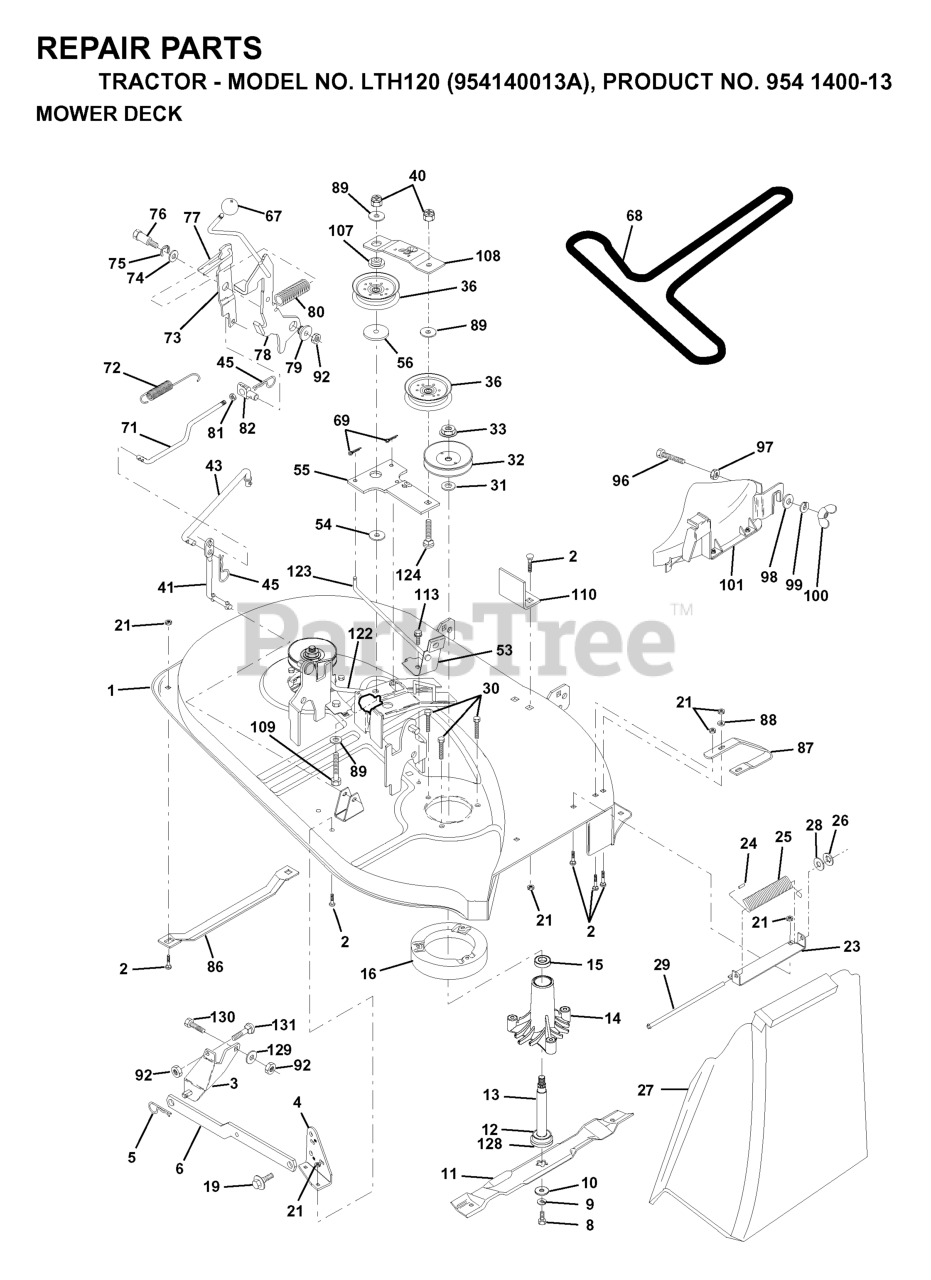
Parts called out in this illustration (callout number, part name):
1	DECK ASSY-WELDMENT
2	RP BOLT 5/16-18 X3/4 ZN/YEL GR
3	BRKT ASM SWAY BAR
4	BRKT DECK SW BAR
5	RETAINER-SPRNG RB
6	REAR SUSP ARM
8	BLADE BOLT
9	LOCKWASHER
10	WASHER.BLADE
11	BLADE 38" V MULCH
12	BEARING.BALL.#6204.(MANDREL)
13	SHAFT ASM VENT
14	HOUSING.MANDREL.VENTED (MACHD)
16	STRIPPER
19	BOLT SHD 5/16-18
21	LOCKNUT
23	BRACKET, DEFLECTOR
24	CAP-SLEEVE LT
25	SPRING TORSION
26	NUT PUSH M
27	SHIELD.DEFLECTOR.MOWER.38.BL
28	Washer 11/32 x 5/8 x 16 Ga SD
29	ROD-HINGE T
30	SCREW
31	WASHER
32	PULLEY MANDREL
33	NUT
36	FLAT IDLER PULLEY
43	CLUTCH ROD SECONDARY
45	RETAINER M
53	BRAKE ASSEMBLY
54	HARDENED WASHER
56	SPACER RETAINER
67	KNOB T (3/8 HOLE)
68	V-BELT TRIPATH
69	COTTER PIN
71	CLUTCH ROD
72	RETURN SPRING
73	ARM CLUTCH SECONDARY
77	KEEPER SPRING
78	ARM ASM CLUTCH PRIMARY
79	BUSHING.FLANGE.E-RING.GROOVE
80	SPRING-CLUTCH (2 2 PW01)
81	NUT
82	TRUNNION.ADJUSTABLE.3/8-16
86	RUNNER-LH M
87	RUNNER.RH.38
88	WASHER M
89	WASHER GT
92	NUT
96	Bolt, Hex Head 3/8-16 x 1-1/4
97	LOCKNUT
98	WASHER
99	WASHER, LOCK 3/8
101	COVER.MULCHING.38" (2 2)
107	SPACER.IDLER.ARM
108	STIFFENER.IDLER.ARM
109	Bolt Hex Fin 3/8-16 UNC x 2-1/2
110	UPSTOP DECK FRONT 38"
113	SCREW.THDROL.5/16-18X3/4.TTY
122	BRAKE ROD LH
123	BRAKE ROD RH
128	WASHER FELT
129	WASHER
131	BOLT D
